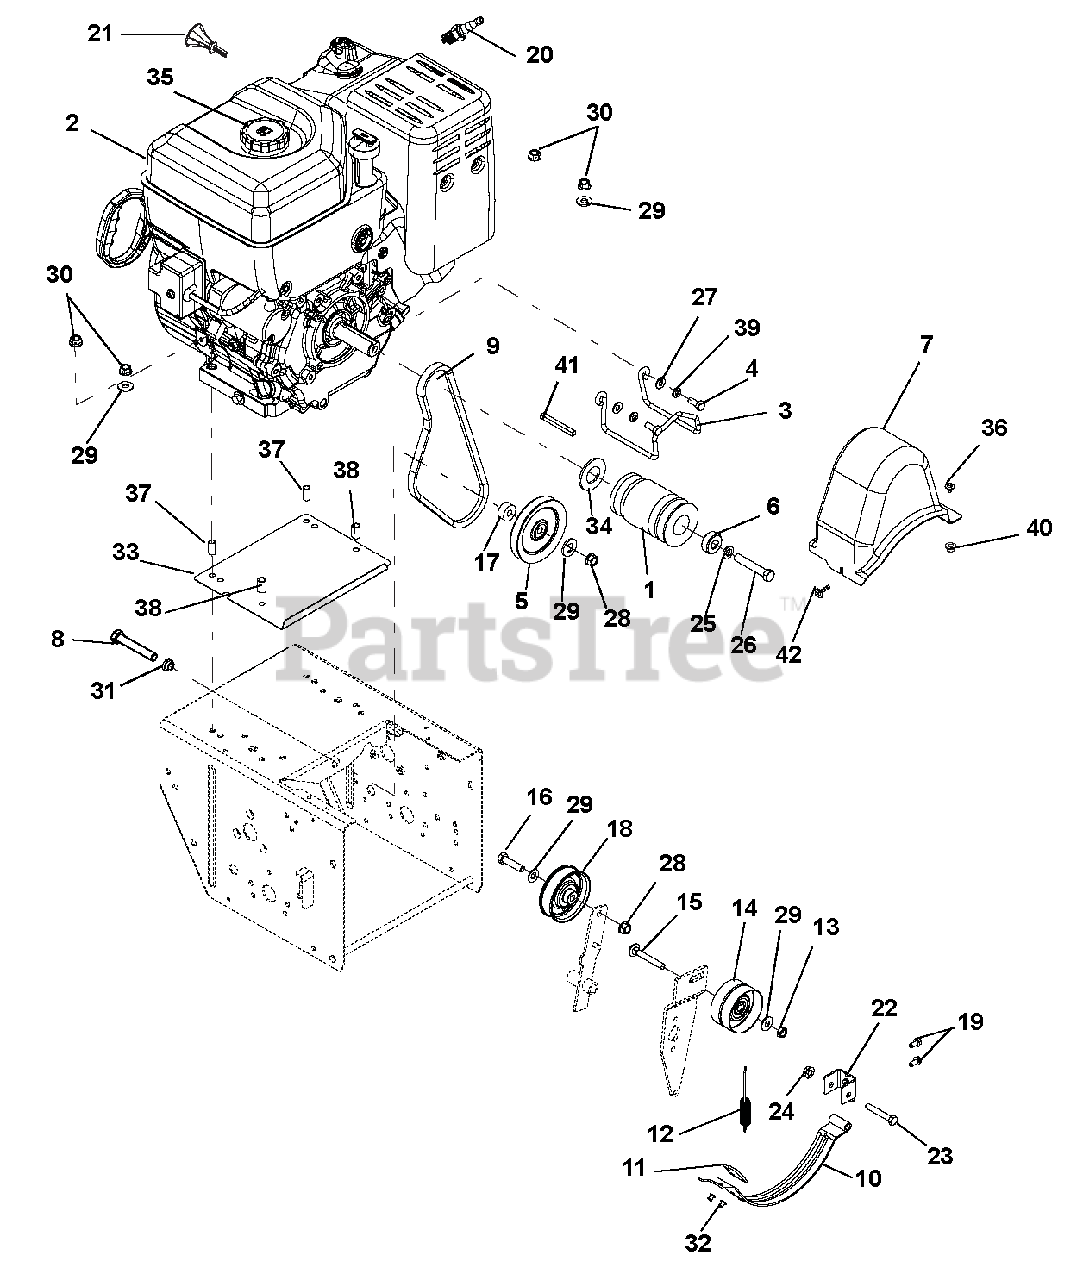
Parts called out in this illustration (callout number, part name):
1	SHEAVE, COMBO HYDRO WHEEL 4L
1	SHEAVE, COMBO HYDRO TRACK 4L
2	ENGINE, BRIGGS PF 2100, 120V
2	ENGINE, BRIGGS PF 2100, 240V
2	ENGINE, BRIGGS PF 2100, 12V
3	FINGER, BELT
4	BLT-HEX .31-24X.75 YWZC GR5
5	SHV, .38"ID X 4.00"OD V-IDLER
6	BSHG-SPACER .47X1.25X.50
7	COVER, BELT-LARGE PRO
8	@BLT-HEX .38-16X2.00 GR5 YWZC
9	V-BELT, 4L-WRAPPED
10	ARM, BRAKE-ATTACHMENT
11	PAD, BRAKE
12	SG-TENS .056X.60X4.40
13	@NUT-LK-CTR-JAM .375-16 YWZC
14	IDLER, FLAT-2.75 OD X .375 ID
15	@BLT-RHDSSQNK .38-16X1.75 G5YZ
16	@BLT-HEX .38-16X1.50 GR5 YWZC
17	BSHG,POCKET .391X.570X1.0X.450
18	IDLER, FLAT - 3.05" X .75"
19	SCR-TAP .25-20X.50 HWH TR YWZ
20	PLUG, SPARK 20HP B&S VANGUARD
21	KEY, IGNITION ROTARY B&S
22	PIVOT, BRAKE
23	@BLT-HEX .31-18X2.00 GR5 YWZC
24	@NUT-LK-TOP-FLG .31-18 YWZC
25	@WSHR-LK .44X.109 REG YWZC
26	BLT-HEX .44-20X2.50 GR5 YWZC
27	@WSHR-FL-STL.344X.688X.065YWZC
28	@NUT-LK-TOP-FLG .38-16 YWZC
29	@WSHR-FL-STL.38X.875X.083 YWZC
30	@NUT-LK-CTR-FLG .31-18 YZ GR F
31	BSHG, FLANGE .391X.56X.313X.75
32	RVT-POP .187 YZ
33	BAFFLE,ENGINE-PRO SERIES
34	WSHR-FL-STL- 1.062X2.0X.134 YZ
35	CAP, FUEL - BRIGGS & STRATTON
36	SCR-TAP .25-20X.50 LGHWH TR YZ
37	BSHG-SLV .325X.400X.795
38	BSHG-SLV .328X.50X.75
39	WSHR-LK .312X.097 HVY YWZC
40	NUT-PUSH .25X.50 O.D.
41	KEY .25X.25X2.25
42	SCR-TAP .25-20X.5 CAPTIVE
